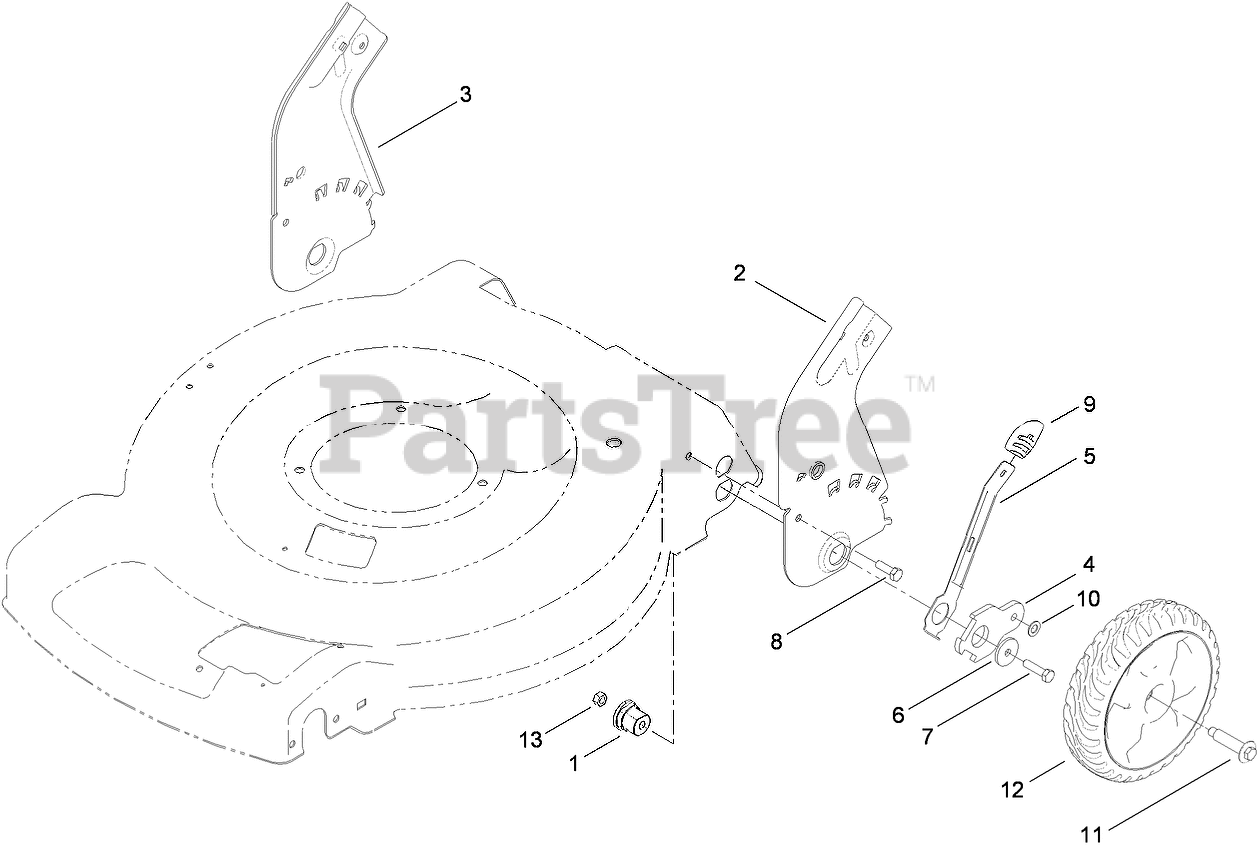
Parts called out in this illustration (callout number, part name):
1	BUSHING-MOUNT, HOC
2	PLATE-HOC, REAR (LH)
3	PLATE-HOC, REAR (RH)
4	ARM-PIVOT, REAR
5	ARM-SPRING, REAR
6	Washer-Flat
7	SCREW-HH
8	SCREW-HH
9	Knob-Lever, HOC
10	WASHER
11	BOLT-SHOULDER
12	8 inch WHEEL ASM
13	NUT-LOCK, NI
